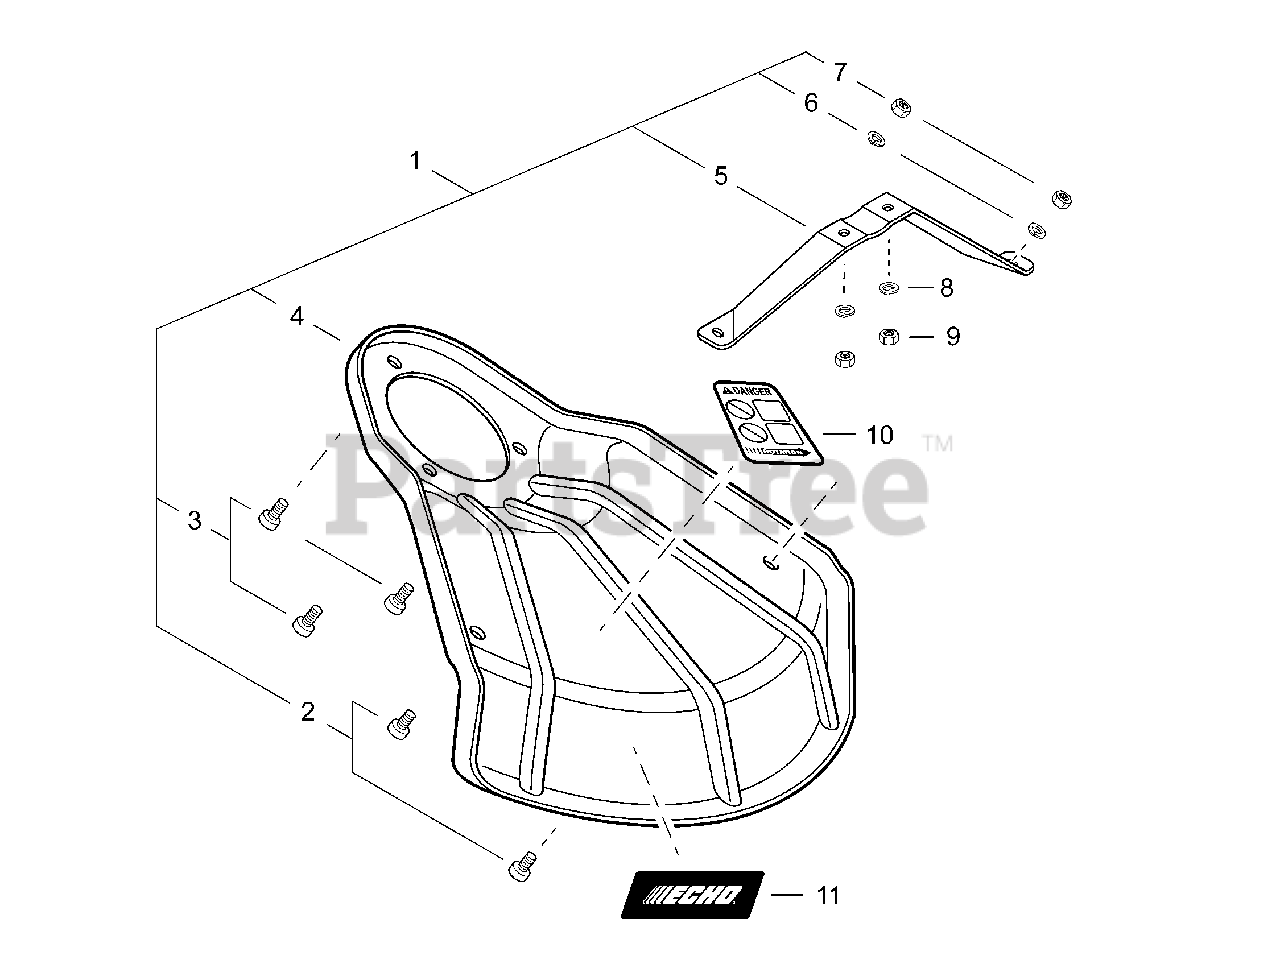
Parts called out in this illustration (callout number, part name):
1	DEBRIS SHIELD KIT - METAL
2	SCREW - 5X8
3	SCREW - 5X10
4	SHIELD, DEBRIS - METAL
5	BRACKET, SHIELD
6	LOCKWASHER - 5
8	LOCKWASHER - 5
10	LABEL - DANGER
11	LABEL - ECHO
